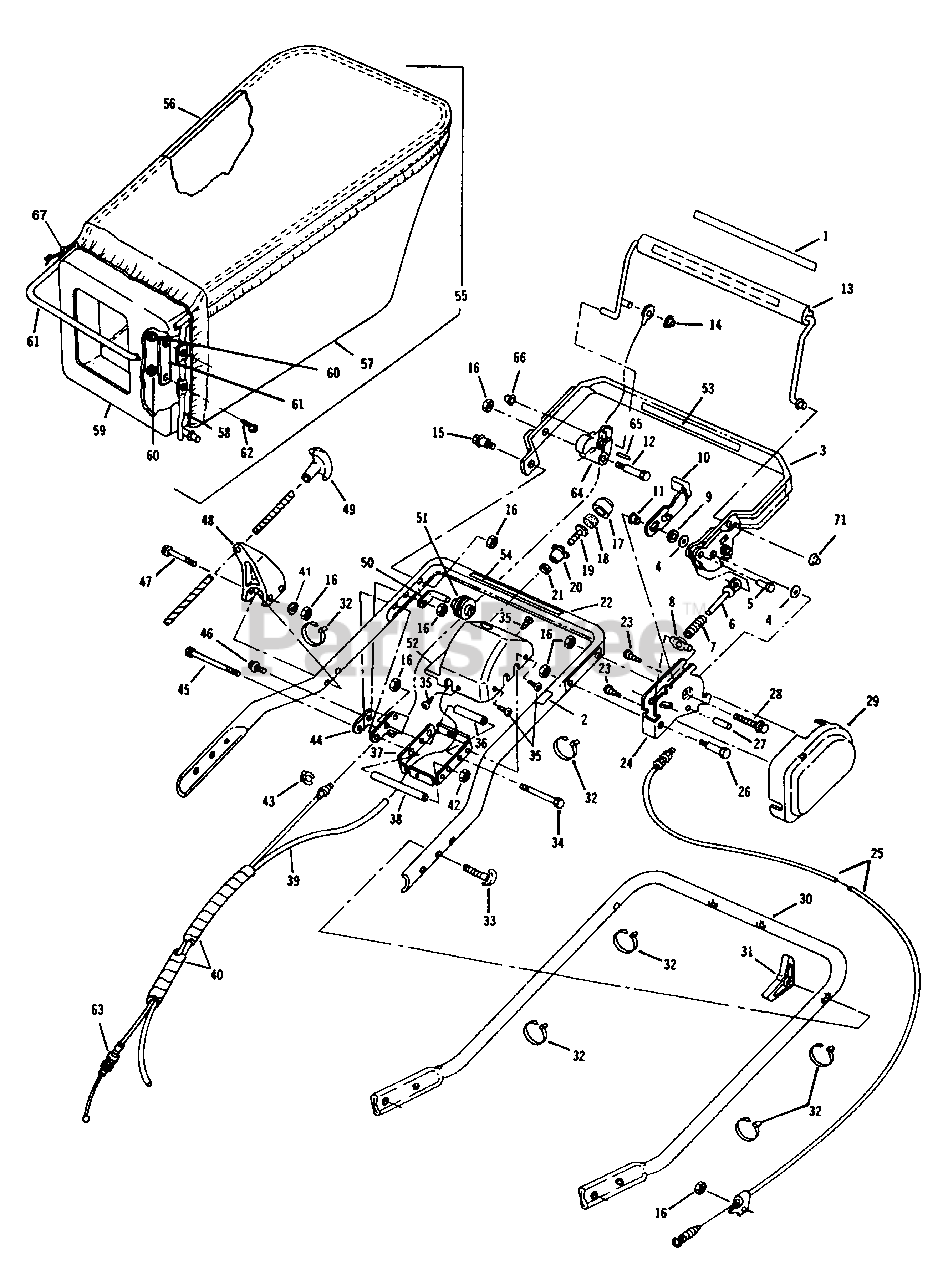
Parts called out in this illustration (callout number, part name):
1	Decal-Engine/Blade
2	Decal-Drive Lockout
3	Top Handle and Grip Assembly
4	Washer-Spring
5	Pin
6	Rod-Spring
7	Spring-Compression
8	Pivot Pin-Spring
9	Washer
10	Lever Lockout
11	Spacer-Flanged
12	Bolt
13	Control Lever and Nut Assem.
14	Nut-Acorn
15	Bolt Shoulder
16	Locknut
17	Primer Bulb
18	Filter
19	Primer Base
20	Cup
21	Locknut
22	Handle Section-Center
23	Screw-Cover
24	Bracket-Control
25	Cable Assembly
26	Bolt-Shoulder
27	Roll Pin
28	Bolt-Shoulder
29	Cover-Lockout
30	Handle-Lower
31	Knob-Folding Handle
32	Tie Strap
33	Screw
34	Screw-Hex Hd. Cap
35	Screw
36	Spacer
37	Plate-Cover Assembly
38	Spacer
39	Tube-Primer
40	Spiral Tubing
41	Washer
42	Jam-Nut
43	Retaining Ring-Cable
44	Bracket-Clutch Cable
45	Screw
46	Screw-Clutch Cable Brk't.
47	Screw-Truss Head
48	Rope Guide Assembly
49	Handle-Starter
50	Pivot Bracket-Pulley
51	Pulley
52	Cover-Primer Housing
53	Decal-Drive Control
54	Decal-Start Instruct
55	Grass Catcher and Bag Assembly
56	Hanger Bag
57	Grass Bag Assembly
58	Latch Bar Assembly
59	Bag Adaptor
60	Nut-Bag Adaptor
61	Bar-Reinforcing
62	Screw-Bar Adaptor
63	Control Cable Assem.
64	Cam and Roll Pin Assem.
65	Roll Pin
66	Pushnut
67	Rope
68	Cam
